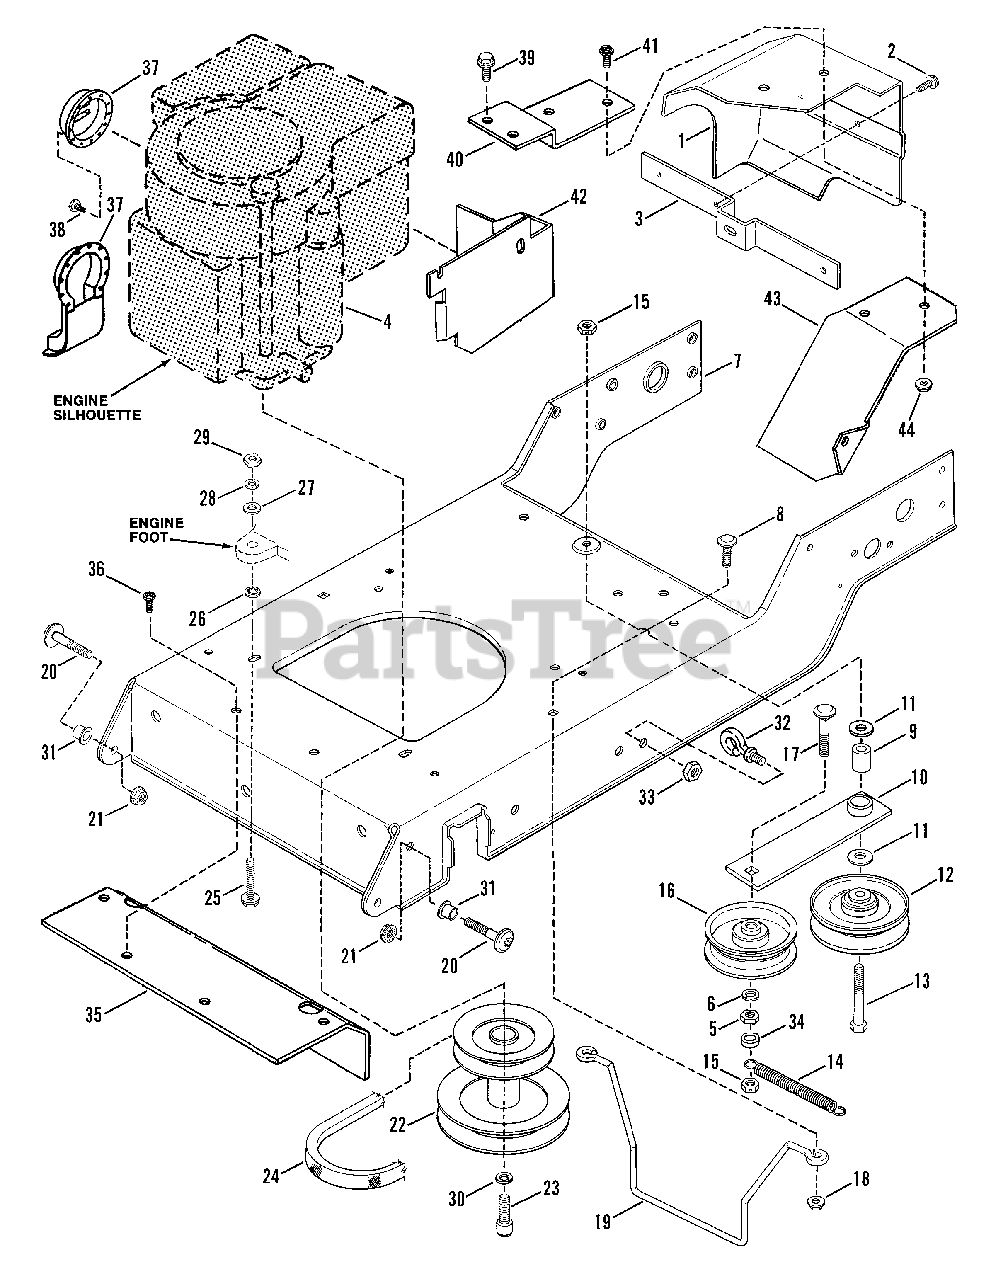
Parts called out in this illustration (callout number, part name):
1	HEAT SHIELD
2	SCREW, #10-24 x 1/2" H.W.S.T.
3	BRACKET, Heat Shield
5	NUT, 3/8-16 Hex
6	LOCKWASHER, 3/8 Split
7	BASE, Engine
8	BOLT, 5/16-18 x 3/4" Short Neck Carriage
9	BUSHING, Idler
10	ARM, Idler
11	WASHER, 3/8" Flat
12	PULLEY, Idler, 4" O.D.
13	BOLT, 3/8-16 x 2-1/4" Hex
14	SPRING, Idler Arm
15	LOCKNUT, 3/8-16 Hex, Center Lock
16	PULLEY, Idler, 3-3/4" O.D.
17	BOLT, 3/8-16 x 2-1/2" Short Neck Carriage
18	LOCKNUT, 5/16-18 Hex Flange
19	GUIDE, Belt
20	SCREW, Shoulder, 3/8-16 x 1-5/8"
21	LOCKNUT, 3/8-16 Hex Flange
22	PULLEY ASSEMBLY, Engine
23	CAPSCREW, 7/16-20 Hex Socket Head
24	V-Belt, Traction Drive, LT12D 33 & LT12D41
25	SCREW, 5/16-1 8 x 1-1/2" Hex Head Cap
26	RETAINER, Bolt
27	WASHER, 5/16 Flat
28	LOCKWASHER, 5/16 Split
29	NUT, 5/16-18 Hex
30	LOCKWASHER, 7/16" Split
31	BUSHING
32	EYE-BOLT
33	LOCKNUT, 5/16-18 Hex
34	SPACER
35	AXLE SUPPORT
36	SCREW, 5/16-18 x 5/8" Truss Hd. Torx
37	DEFLECTOR, Exhaust
38	SCREW, #8-18 x 3/8" Hex Hd.Tapered
39	SCREW, #10-24 x 1/2" Slotted H.W.H.
40	BRACKET, Heat Shield
41	BOLT, 1/4-20 x 5/8" Hex Flange Lock
42	AIR DUCT
43	SHIELD, Carburetor
44	NUT, 1/4-20 Hex Fl. Lock
